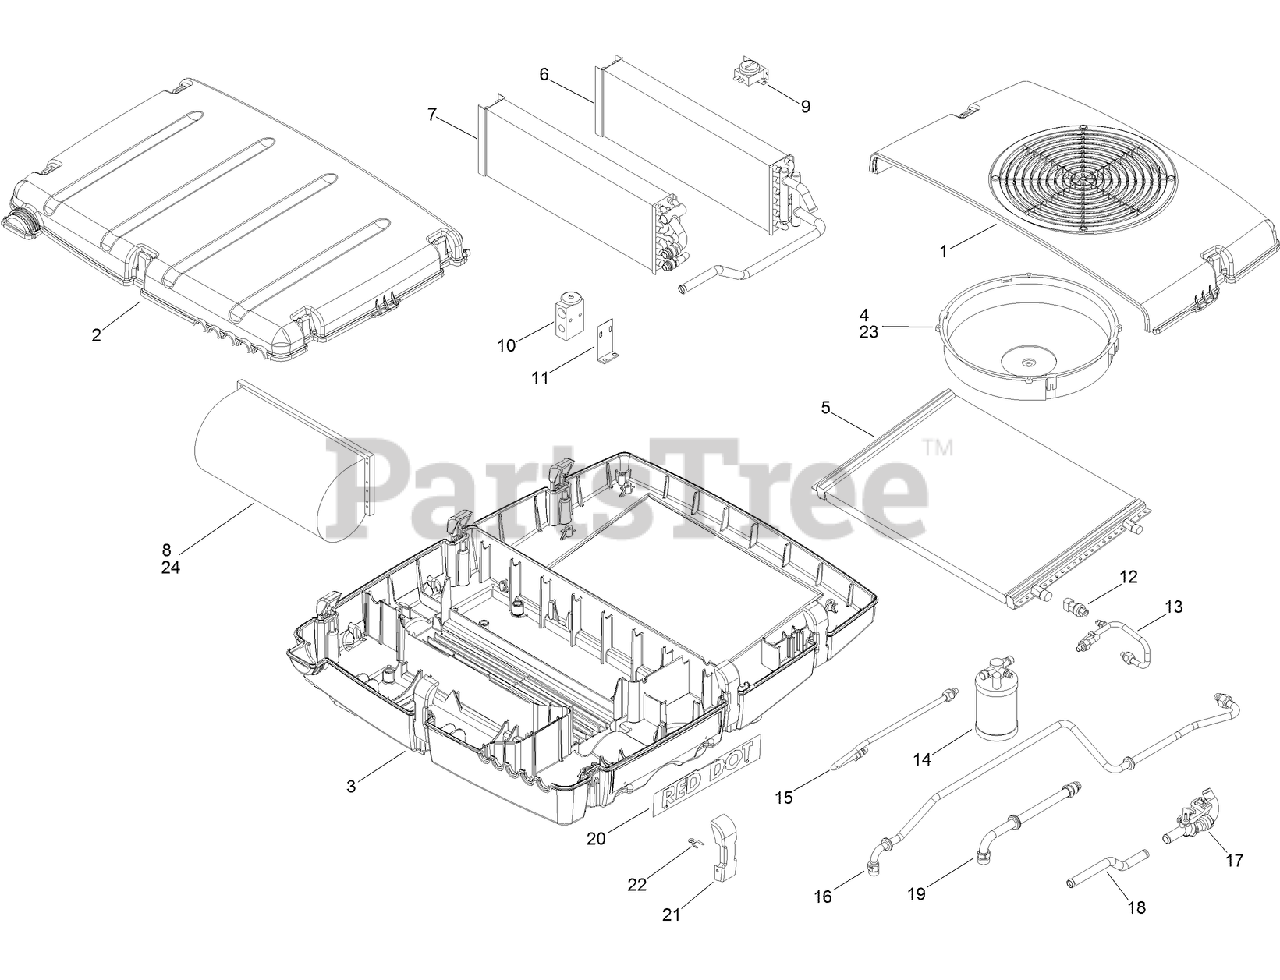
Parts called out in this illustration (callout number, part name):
1	COVER-CONDENSER
2	COVER-EVAPORATOR
3	HOUSING
4	FAN/MOTOR ASM
5	CONDENSOR
6	HEATER CORE ASM
7	EVAPORATOR ASM
8	MOTOR BLOWER ASM
9	THERMOSTAT
10	VALVE-EXPANSION
11	BRACKET-VALVE, EXPANSION
12	SWITCH-PRESSURE
13	TUBE-DRIER/RECIEVER
14	DRIER-RECIEVER
15	TUBE-CONDENSER
16	TUBE-INLET, CONDITIONER
17	VALVE-WATER
18	TUBE-HEATER
19	TUBE-OUTLET
20	PLACARD
21	LATCH-CENTER, OVER
22	RETAINER-LATCH, PIVOT
